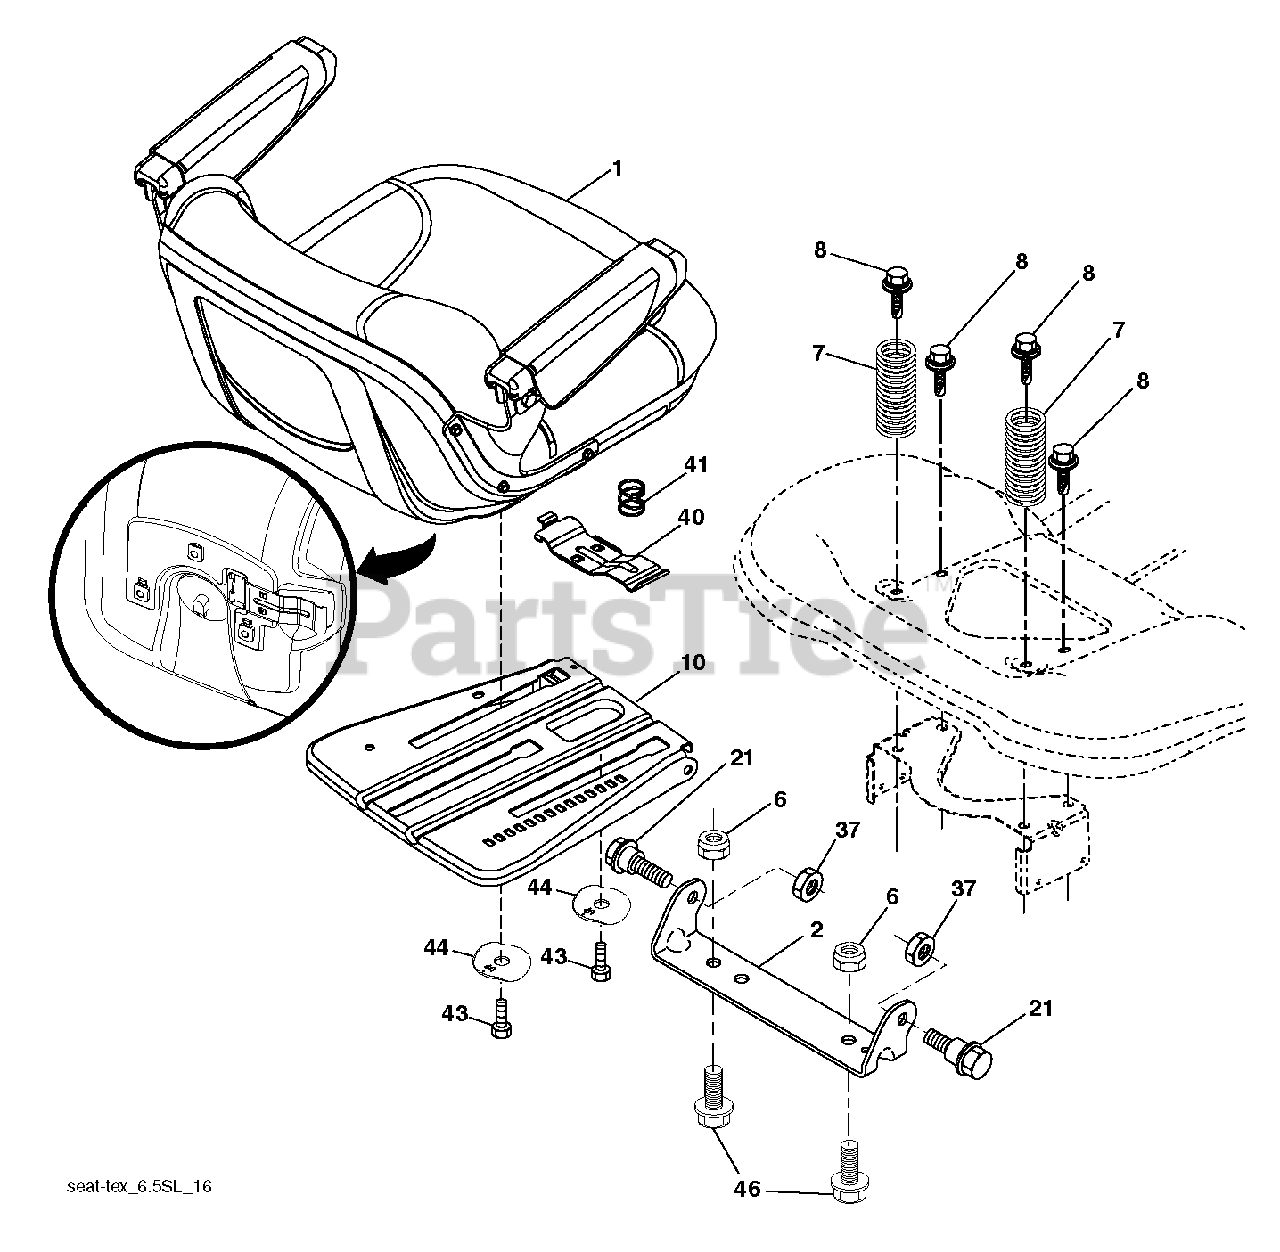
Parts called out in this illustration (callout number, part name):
1	SEAT.TH154.498GY.HUS.
2	BRKT.PIVOT.FENDER
6	NUT
7	SPRING.COMPRESS.SEAT.
8	BOLT, 5/16-18 X 1 3/4
10	Seat Slide Plate, Pnt
21	BOLT.5/16-18X5/8.SHOULDER
37	NUT.71038.31-18.HEX.NYLOCK
40	HANDLE.SLIDE.SEAT.TEX.GREY
41	SPRING.LATCH.SEAT.TEX
44	Winged Washer, 38Id 1
46	BOLT.3/8-16X1;1.25OD.WSHR.SEMS
